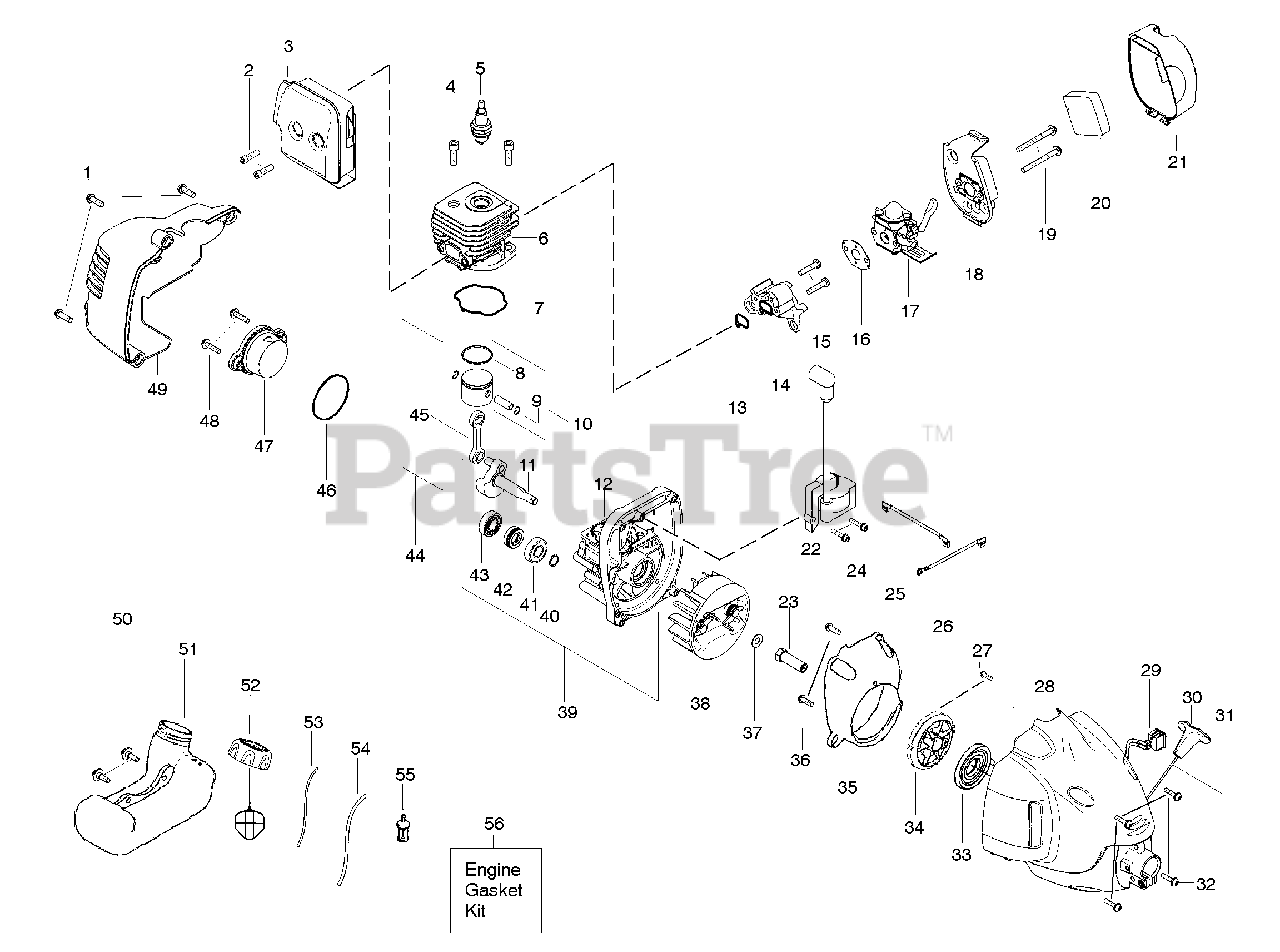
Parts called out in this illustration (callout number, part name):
2	Bolt-Muffler
3	Assy-Muffler/Shield
4	Screw-Cylinder
5	Spark Plug (RCJ 6Y)
6	Cylinder
7	Seal-Cylinder (kit)
8	Piston Ring
9	Retainer-Piston Pin
10	Kit - Piston
11	Assy-Crankshaft
12	Assy-Crankcase
13	Seal-Cyl/Carb.(kit)
14	Adapter-Carb.
16	Gasket-Carb. (kit)
17	Kit-Carb. Zama (C1U-W18)
17	Kit-Carb. Walbro (WT-669)
20	Foam-Air Filter
21	Cover-Air Box
22	Kit - Ignition Module
23	Coupling-Drive
25	Assy-Leadwire
26	Assy-Ground Wire
28	Assy.-Fan Hsg
29	Kit-Switch
30	Handle-Starter
31	Kit - Rope
32	Screw
33	Spring-Starter
34	Kit-Starter Pulley
35	Baffle
37	Washer-Flat
38	Assy-Flywheel
39	Assy-C'case & C'shaft
40	Retain. Ring-C'shaft
41	Outer Bearing
43	Inner Bearing
44	Kit-Piston/Rod
45	Assy-Connecting Rod
46	O-Ring-C'case (kit)
47	Assy-Plug
49	Shroud-Rear
50	Retainer-Tank
51	Assy-Fuel Tank
52	Assy-Fuel Cap
53	Kit-Fuel Line (Small)
54	Kit-Fuel Line (Large)
55	Assy-Fuel Pickup
56	Kit-Engine Gasket
